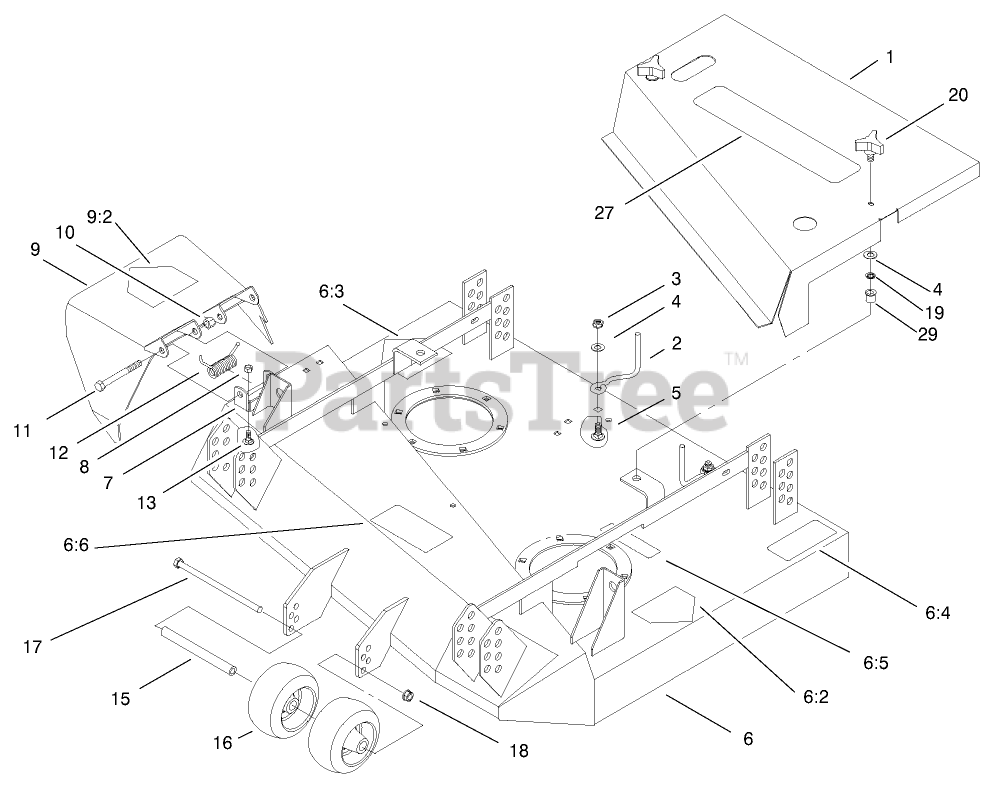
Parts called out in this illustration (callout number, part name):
2	ROD-BELT
3	NUT-HF
4	WASHER-FLAT
5	SCREW-CARR
6	DECK ASM
6:2	DECAL-DANGER
6:3	DECAL-DANGER
6:4	DECAL-TORQUE
6:5	DECAL-DANGER
6:6	DECAL-DANGER, THROWN OBJECT
7	BRACKET-PIVOT
8	NUT-LOCK, CONE
9	DEFLECTOR ASM
9:2	DECAL-DANGER
10	NUT-HEX
11	SCREW-HH
12	SPRING
13	SCREW-CARR
15	SPACER-WHEEL
16	WHEEL-GAGE
17	SCREW-HH
18	NUT-LOCK, NI
19	RING-RETAINING
27	DECAL-36"
29	INSERT-NUT
